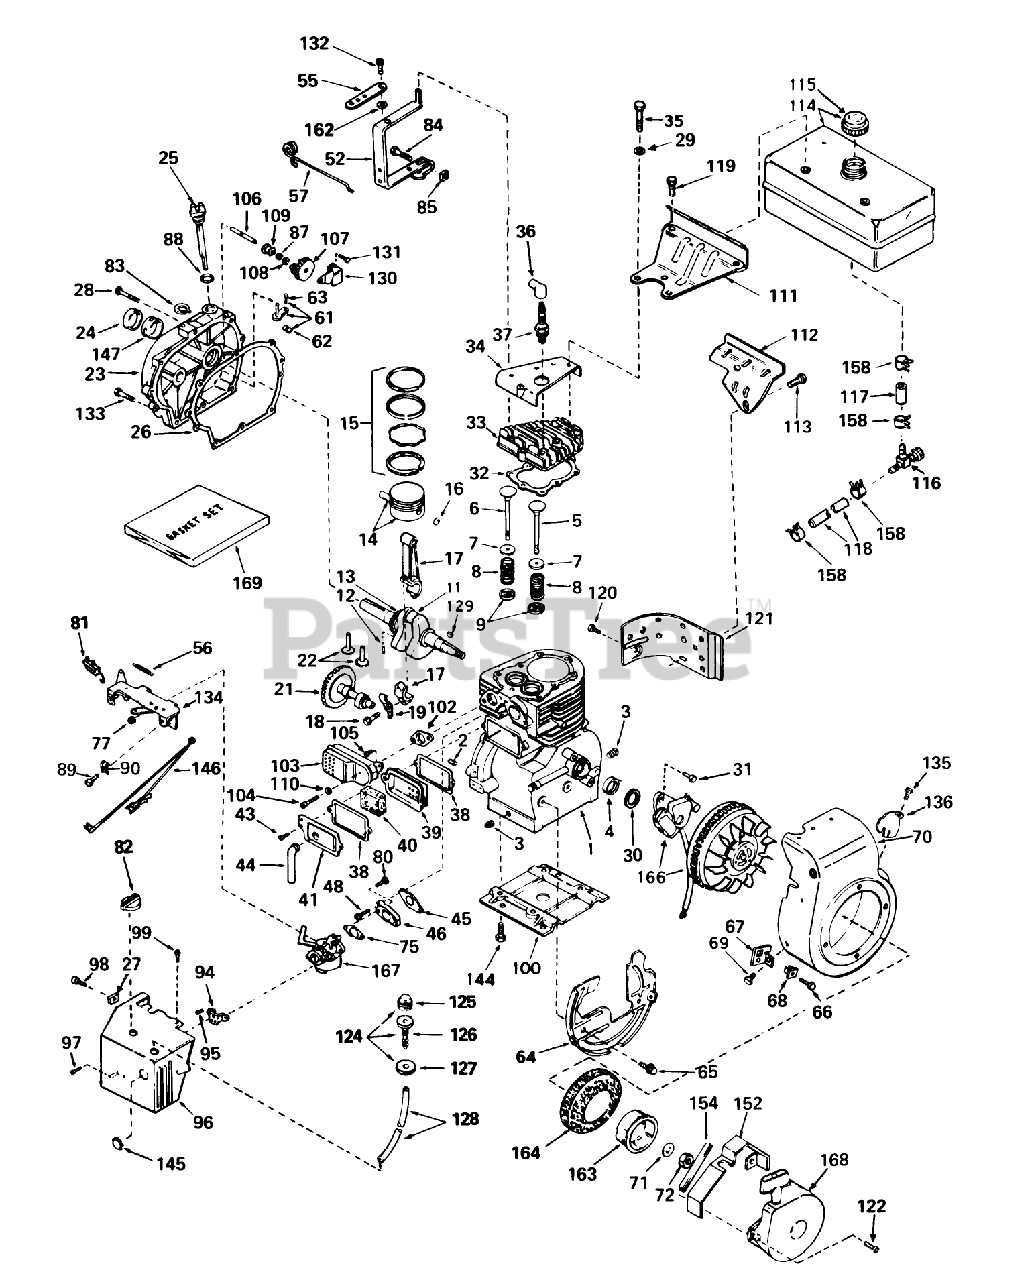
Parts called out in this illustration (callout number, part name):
1	Cylinder Assy. (Incl. Nos. 2, 3 4)
2	Pin-Dowel
3	Plug-Drain, Oil (SQH 1/4-18)
4	Oil Seal
5	Valve, Intake (Standard)(Incl. No. 9)
5	Valve, Intake (1/32" oversize)(Incl. No. 9)
6	Valve, Exhaust (Standard)(Incl. No. 9)
6	Valve, Exhaust (1/32" oversize)(Incl. No. 9)
7	Cap-Spring, Valve
8	Spring-Valve
9	Keeper-Spring, Valve
11	Crankshaft Assy. (Incl. Nos. 12 13)
12	Pin, Groove
13	Gear-Crankshaft
14	Piston Pin Assy. (Std.) (Incl. Ref. #20)
14	Piston, Pin Ring Assy. (Std.) (Incl. Ref. #19A, 20 21)
14	Piston Pin Assy. (.010 oversize) (Incl. Ref. #20)
14	Piston, Pin Ring Assy. (.010 oversize) (Incl. Ref. #19A, 20 21 )
14	Piston Pin Assy-. (.020 oversize) (Incl. Ref. #20)
14	Piston, Pin Ring Assy. (.020 oversize) (Incl. Ref. #19A, 20 21)
15	ORing
15	Ring Set (.010" OS)
15	Ring Set (.020" OS)
17	Rod Assy., Connecting (Incl. Nos. 10 18)
18	Bolt, Connecting Rod
19	Dipper-Oil
21	Camshaft
22	Lifter-Valve
23	Cover, Cylinder (Incl. Nos. 24 106)
24	Oil Seal
25	Dipstick, Oil (Incl. No. 30)
26	Gasket-Cover, Cylinder
27	Nut-U Type
28	Screw (1/4-20 x 1-1/4)
29	Washer-Flat
30	Gasket Stator
31	Screw
32	Gasket-Cylinder Head
33	CYLINDER HEAD
34	Cover-Head, Cylinder
35	Screw (5/16-18 X 2-1/2)
36	Cover-Spark Plug
37	Plug, Spark (J17LM or equiv.)
37	Plug, Spark (Champion RCJ-8)
38	Gasket-Breather
39	Body-Breather
40	Element-Breather
41	Cover-Valve
43	Screw
44	Tube-Breather
45	Gasket-Intake
46	Flange, Carburetor (Incl. Nos. 77 80)
48	Screw
52	Lever, Governor
56	Spring, Extension
57	Link, Governor to Throttle
61	Rod, Governor (Incl. Nos.62 63)
62	Yoke-Governor
63	Screw (6-40x5/16)
64	Baffle Blower Housing
65	Screw (1/4-20x19/32)
66	Screw
67	Bracket
68	Grommet
69	Screw, Hex Hd.
70	Housing, Blower (Incl. Ref. #135 136)
71	Washer
75	Gasket-Carburetor
77	Nut and Lock Washer (1/4-28)
80	Screw
81	Terminal
82	Knob-Control
83	Ring-Retaining
84	Screw
85	Nut-Lock
87	Washer-Flat
88	Gasket
89	Screw (10-32 x 3/8)
90	Conduit
94	Bracket-Choke
95	Screw (10-32 x 1/2)
96	Cover, Carburetor
97	Screw (8-32 X 5/16)
98	Screw (8-32 x 3/8)
99	Screw (10-32x1/2)
100	Base Engine
102	Gasket Exhaust
103	Muffler
104	Screw (5/16-18 X 2)
105	Screw
106	Shaft-Governor
107	Governor Gear ASM
108	Ring-Retaining
109	Spool-Governor
110	Washer
111	Bracket-Fuel Tank
112	Bracket-Fuel Tank
113	Screw (1/4-20x19/32)
114	Tank Assy., Fuel (Incl. Ref. #115)
115	Cap, Fuel
116	Valve-Shut Off
117	Line-Fuel (8.62)
118	Line-Fuel
119	Screw (1/4-15x7/8)
120	Screw
121	Emnsion, Blower Housing
122	Screw
124	Primer Assy. (Incl. Nos. 89, 90 91)
125	Bulb, Primer
126	Body, Primer
127	Retainer, Primer Bulb
128	Line, Primer
129	Key-Flywheel
130	Bracket, Governor
131	Screw (10-32 x 35/64)
132	Screw
133	Screw
134	Control Assy.,Remote Speed (Incl. No. 56)
135	Screw, Pan Hd.
136	Screw
144	Screw
145	Plug
146	Wire, Ground
147	Bushing-Crankshaft
152	Guard-Starter
154	Seal, Snowguard
158	Clamp-Line, Fuel
162	Washer-Lock
163	Cup-Starter
164	Screen, Air
166	Magneto
167	Carburetor (Incl. No. 75)
168	Starter Assy., Rewind
169	Gasket Set
